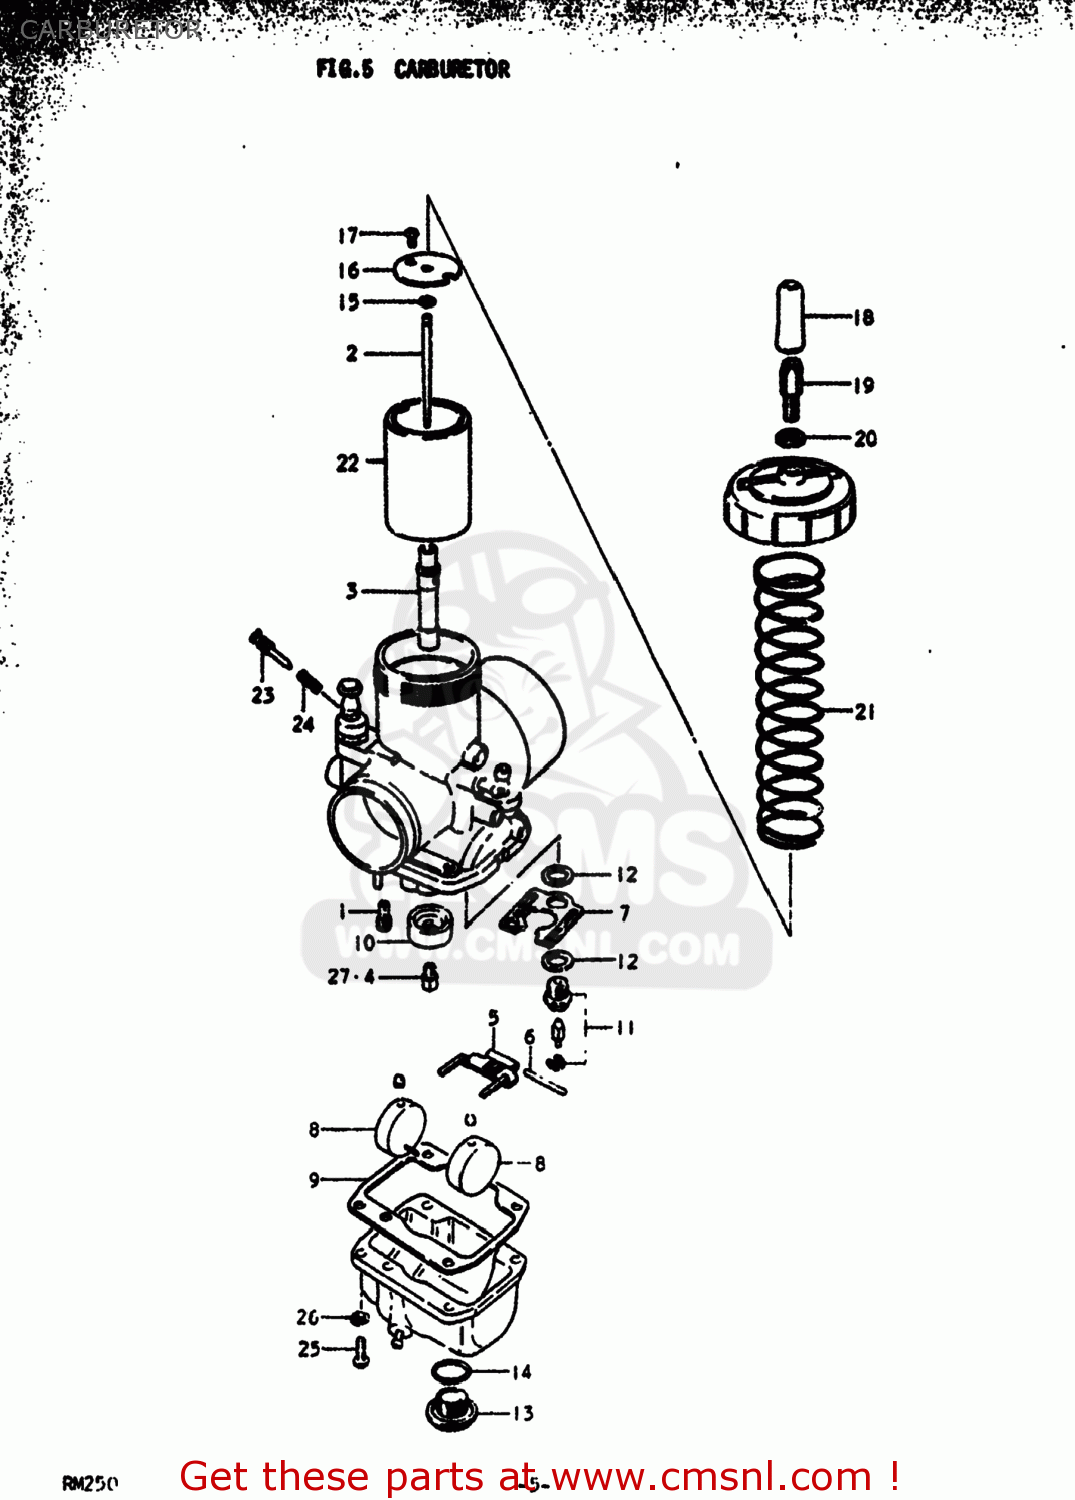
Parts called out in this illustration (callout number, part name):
0	CARBURETOR ASSEMBLY
1	JET,PILOT(45)
2	JET,NEEDLE(6FJ6-3)
3	JET,NEEDLE
4	JET
5	ARM,FLOAT
6	PIN,FLOAT
7	PLATE
8	FLOAT
9	GASKET,FLOAT CAHMBER (NAS)
10	RING
11	VALVE ASSEMBLY,NEEDLE
12	GASKET,MAIN JET HOLDER (NAS)
13	SCREW,GUIDE
14	O-RING
15	CLIP
16	CLIP
17	SCREW
18	CAP,CABLE ADJUSTER
19	ADJUSTER,CABLE
20	NUT
21	SPRING
22	VALVE,THROTTLE
23	SCREW,PILOT AIR
24	SPRING
25	SCREW
26	LOCK WASHER
27	JET
